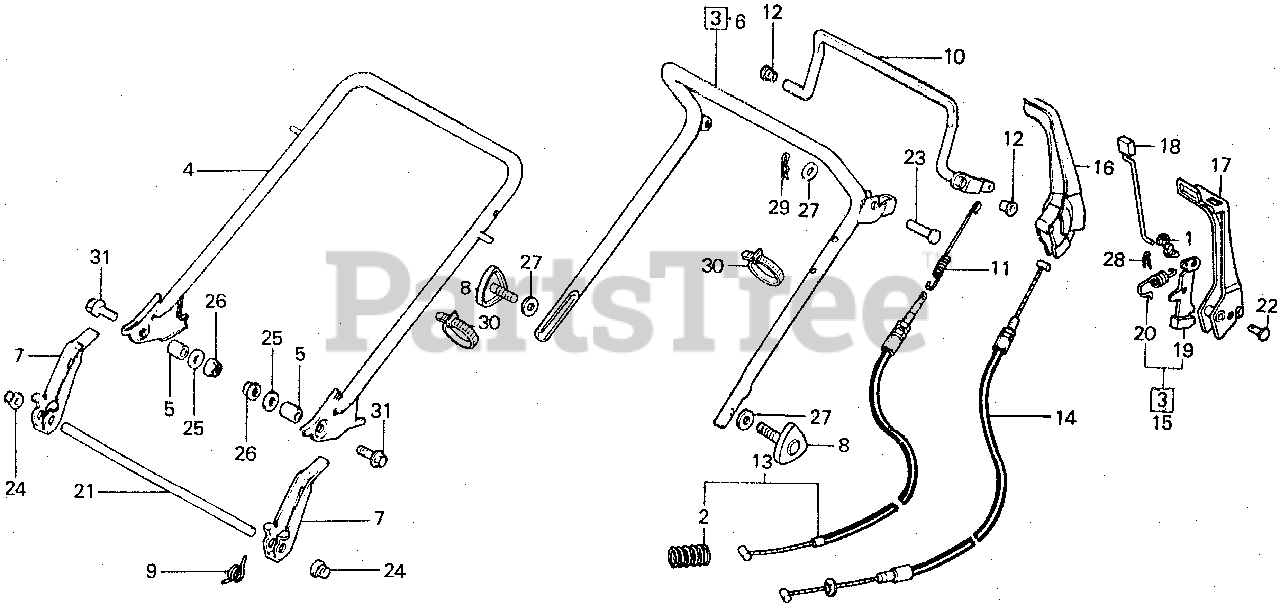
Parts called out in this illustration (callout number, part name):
1	JOINT, ROD
2	SPRING, CLUTCH RETURN (NOT AVAILABLE)
3	HANDLE SET (UPPER)
4	HANDLEBAR (LOWER)
5	COLLAR (LOWER)
6	HANDLE SET (UPPER)
7	LEVER, LOCK
8	GRIP, HANDLE JOINT
9	SPRING, HANDLE (NOT AVAILABLE)
10	LEVER, CLUTCH (NOT AVAILABLE)
11	SPRING, CLUTCH (NOT AVAILABLE)
12	BUSH, CLUTCH LEVER
13	CABLE A, CLUTCH
14	CABLE, ROTO-STOP CLUTCH
15	LEVER SET, LOCK (NOT AVAILABLE)
16	LEVER, ROTO-STOP CLUTCH
17	LEVER, ROTO-STOP (NOT AVAILABLE)
18	ROD, RATCHET PUSH (NOT AVAILABLE)
19	LEVER, LOCK
19	LEVER, LOCK (NOT AVAILABLE)
20	SPRING, RATCHET RETURN
21	SHAFT, SHIELD
22	PIN, SEAT HINGE
23	PIN, CLUTCH LEVER (NOT AVAILABLE)
25	WASHER (23X8.3X3.2)
26	NUT, FLANGE (8MM)
27	WASHER, PLAIN (8MM)
28	PIN, LOCK (6MM)
29	PIN, LOCK (8MM)
30	BAND B2, WIRE
31	BOLT, FLANGE (8X32)
